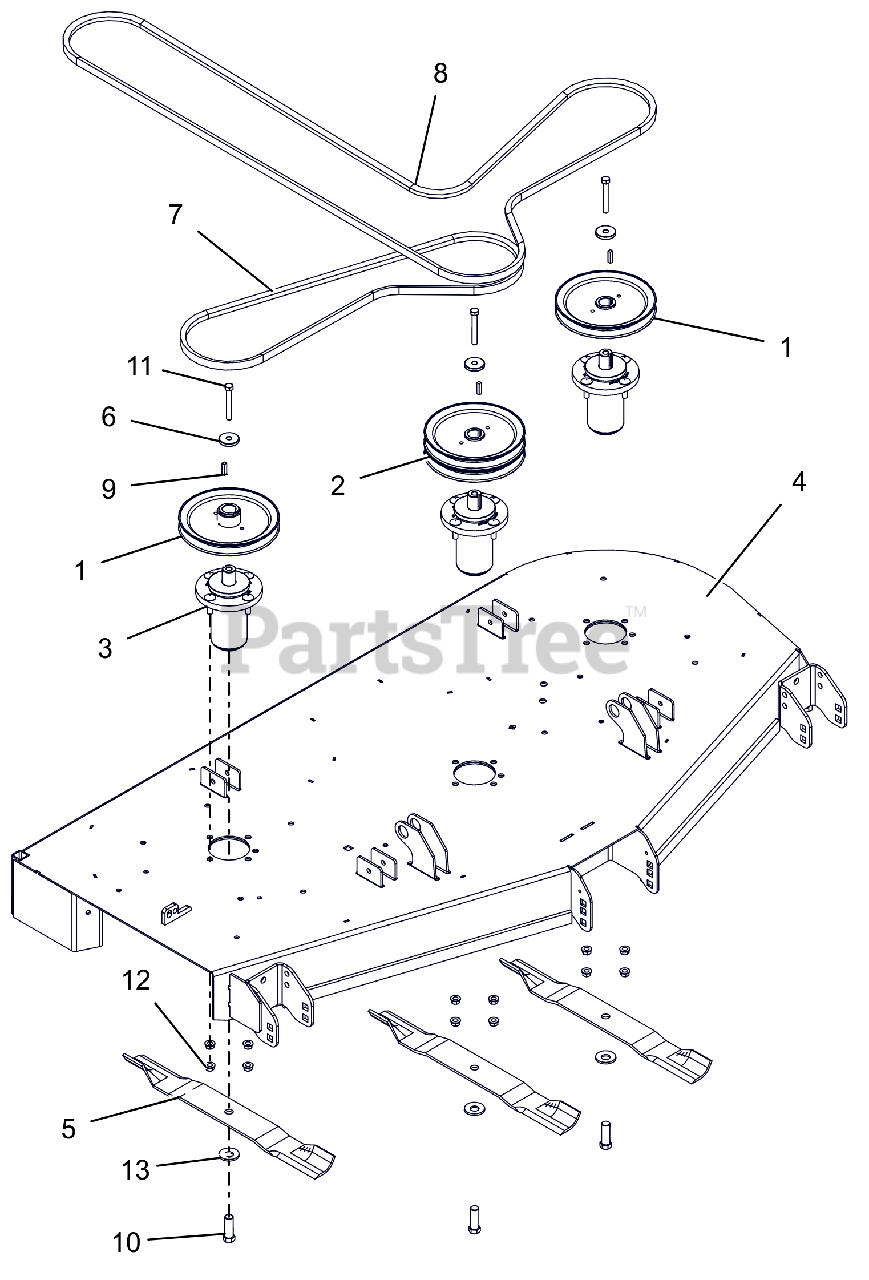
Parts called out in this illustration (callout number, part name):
1	PULLEY, V-7.50 OD X 1"ID
2	PULLEY, DOUBLE 1"X7.50"&7.50" (BLACK)
3	ASM, MAINT FREE ALUM SPINDLE
4	KIT,DECK-60" W/DECALS-GRAVELY
5	BLADE, 20.5"
6	RETAINER, SHEAVE
7	V-BELT, B-COGGED
8	V-BELT, HB SECTION
9	KEY, SQ .25X.25X1.00 RC 40-50
10	BLT, HEX .62-18X1.75 G8 ZCC
11	BLT, HEX .38-16X2.75 G8 ZCC
12	NUT-LK-CTR-FLG .375-16 GF ZCC
13	WSHR-BLVL .669X1.535X.138
